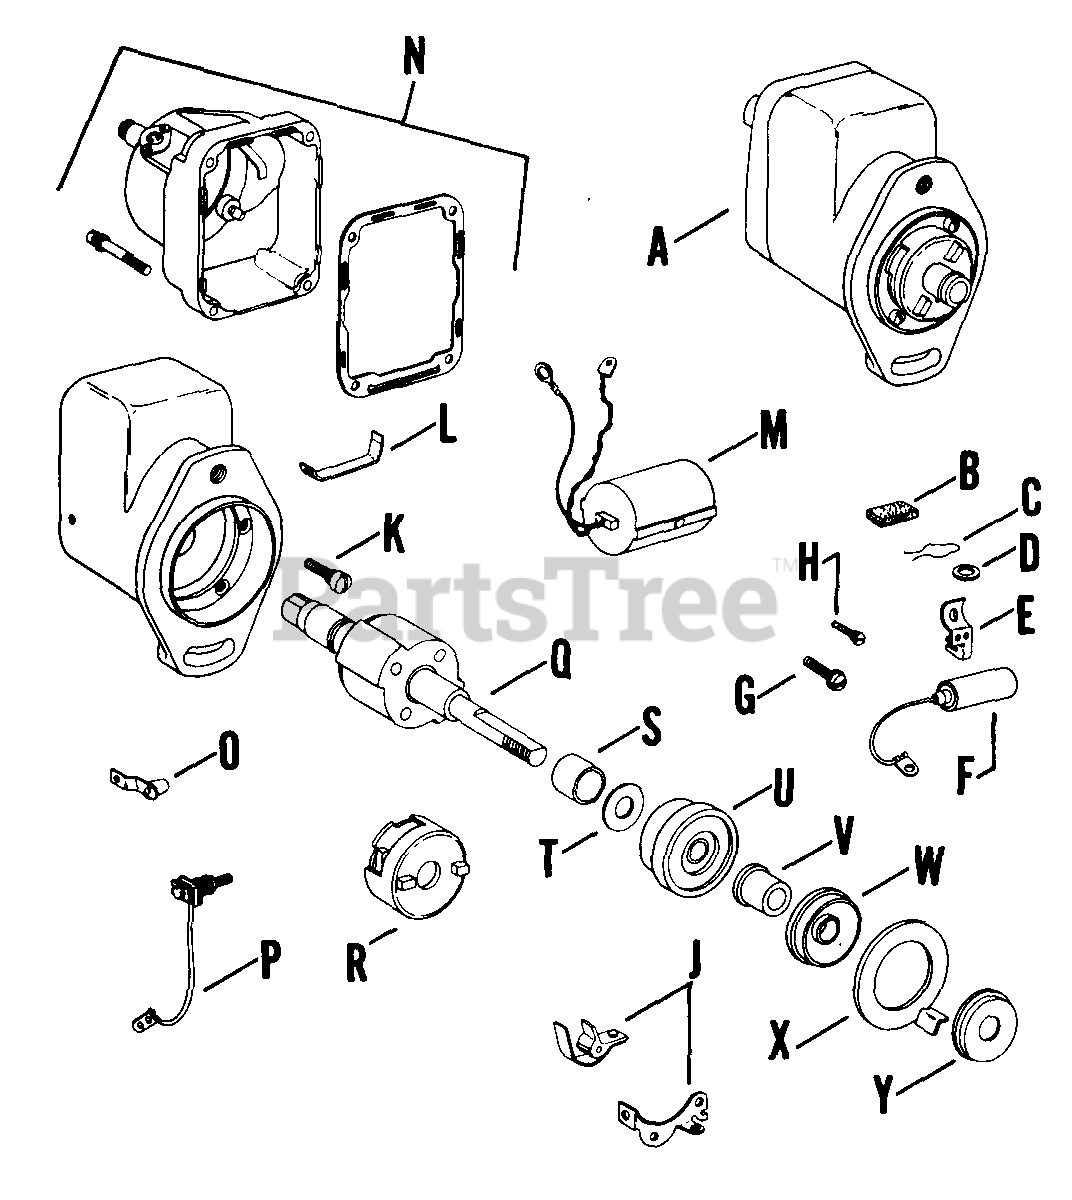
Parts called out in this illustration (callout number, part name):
A	MAGNETO - USE A-270966
C	LOCK - DISCONTINUED
F	CONDENSER - DISCONTINUED
M	COIL - DISCONTINUED
N	COVER - DISCONTINUED
O	BUTTON - DISCONTINUED
P	UNIT - DISCONTINUED
Q	ROTOR - DISCONTINUED
U	HOUSING - DISCONTINUED
W	SEAL - DISCONTINUED
X	STOP - DISCONTINUED
Y	OIL SLINGER - DISCONTINUED
